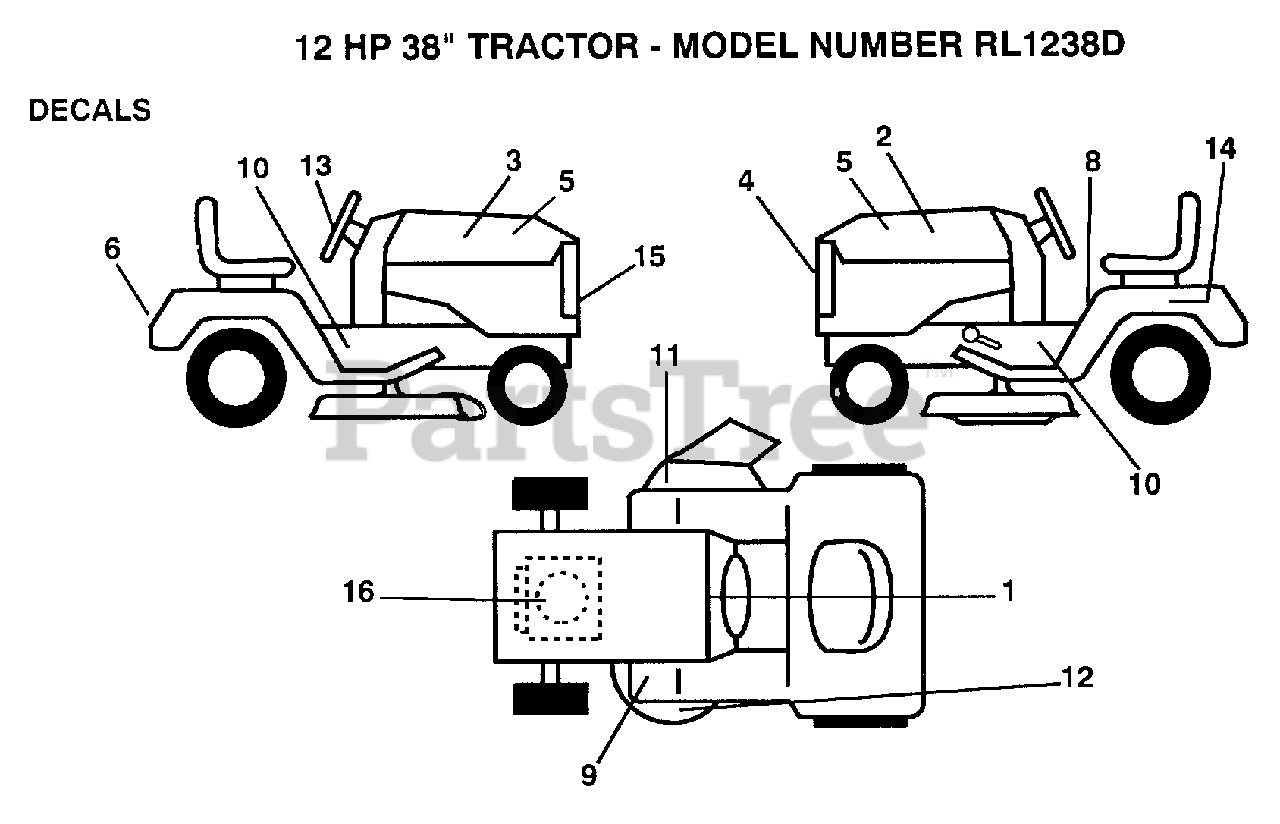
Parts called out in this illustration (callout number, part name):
4	GRILL DECAL
5	"DECAL,HOOD"
6	FENDER DECAL
8	DECAL CAUTION
9	DECAL T
11	DECAL WARNING
12	DECAL YT
13	"DECAL,STR WHL"
14	DECAL
16	DECAL.ENG.271967
